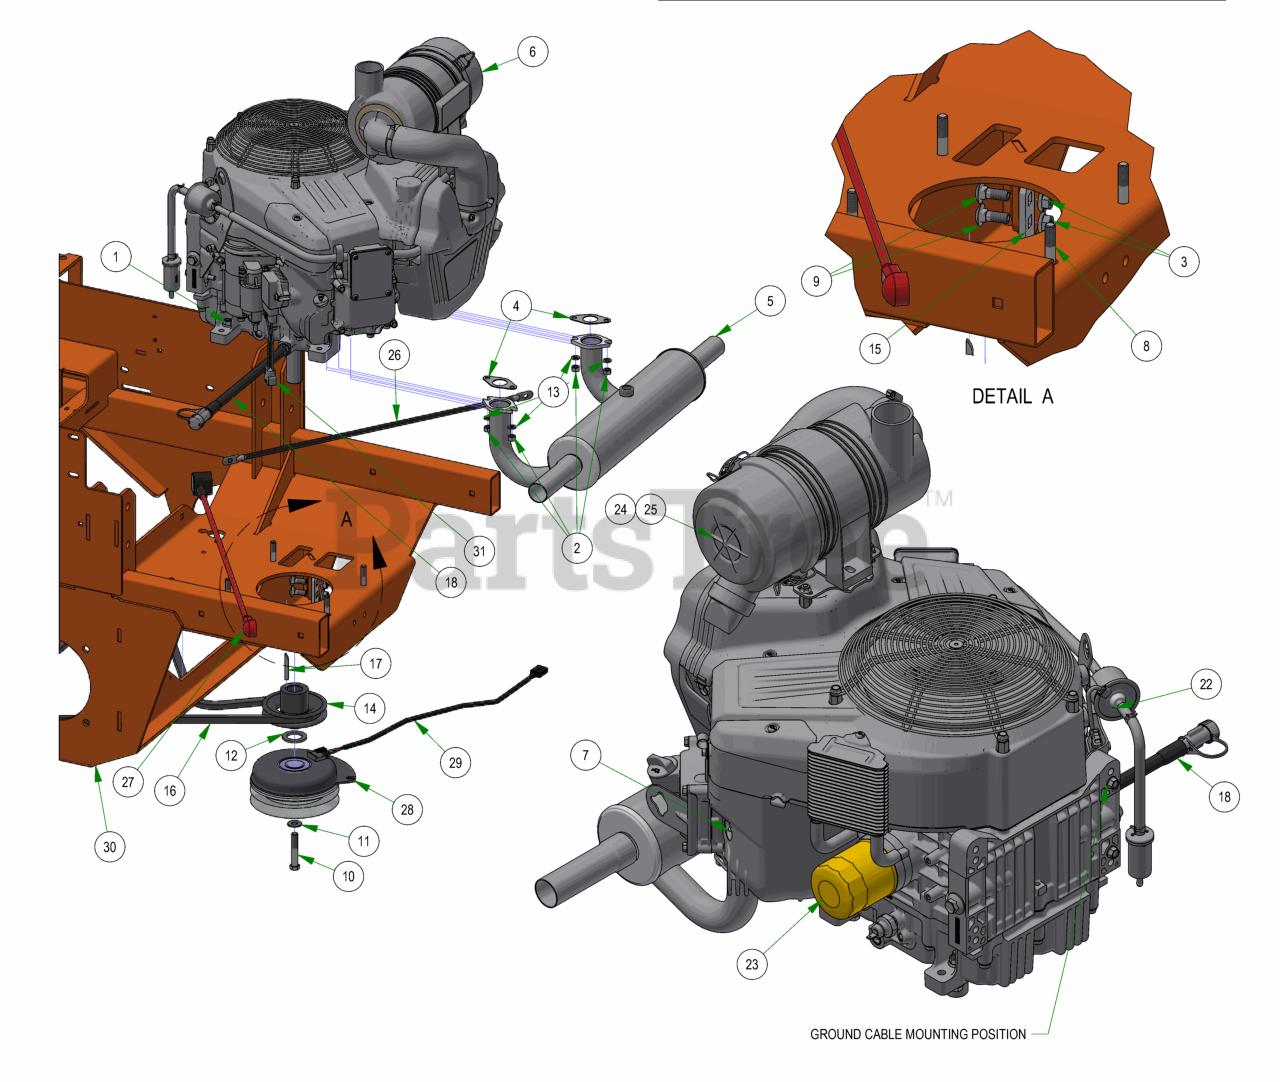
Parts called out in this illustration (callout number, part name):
1	3/8-16 HEX FLANGE TOP LOCKNUT ZINC
2	M8-1.25 DIN 934 HEX NUT (CL.8) ZINC
3	3/8-16 NYLON INSERT FLANGE LOCKNUT (GR.F) ZINC
4	Exhaust Gasket for 23 Vanguard
5	Muffler for 36Hp Vanguard
6	2019 VANGUARD EFI 37 HP 993cc VERTICAL SHAFT
7	Spark Plug
8	3/8-16x1-3/4 Gr5 Hex Flange Screw Zinc Clear
9	3/8-16 X 1 CARRIAGE BOLT (GR.5) ZINC
10	7/16-20 X 2-1/2 HEX Bolt GR 8 W/ Patch
11	3/8 FLAT WASHER USS (1" OD) ZINC
12	1.140 ID X 1.750 OD X .132 THICK FLAT WASHER PLAIN
13	5/16 SPLIT LOCKWASHER ZINC
14	4 3/4 Motor Pulley
15	Rebel Clutch Tab
16	2019 Rebel Pump Belt
17	1/4 X 2 SQ MACHINERY KEY 1018 STL PLAIN
18	11 3/4" Oil Drain Hose
19	Oil Drain Cap
20	Sealing Washer for Barb to M14
21	Barb to M14
22	Universal Inline Fuel Filter
23	Oil Filter
24	Canister Air Filter- Outer
25	Canister Air Filter- Inner
26	24" Black Cable
27	24" Red Battery Cable
28	Clutch Assembly
29	Clutch Pigtail
30	2023 Rebel Frame - Painted
31	2019 Harness Adaptor - Vanguard 37 EFI Vert/Horiz
